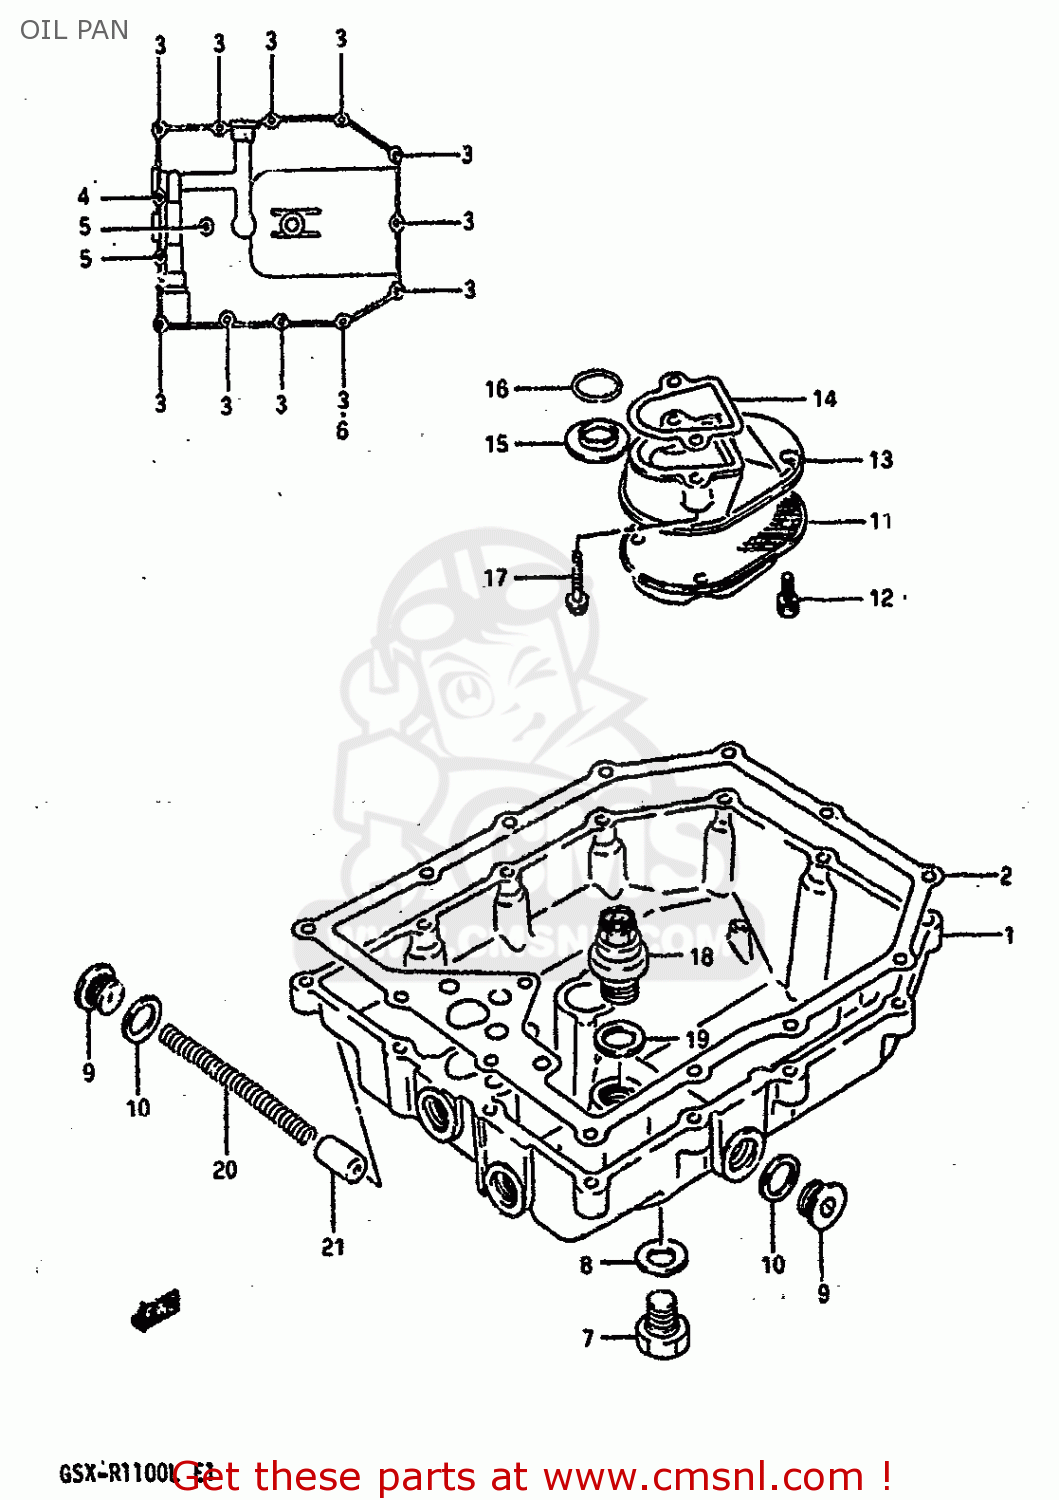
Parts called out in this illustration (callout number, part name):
1	PAN,OIL
2	GASKET,OIL PAN (NA)
3	BOLT
4	BOLT
5	BOLT
6	GASKET(5.8X11X1.2) (NAS)
7	PLUG
8	GASKET(14X19.2X2) (NAS)
9	PLUG
10	GASKET(16X22X2) (NAS)
11	STRAINER,ENGINE OIL
12	BOLT
13	PROTECTOR,OIL STRAINER
14	GASKET,PROTECTOR (NA)
15	GASKET,OIL OUTLET (NAS)
16	O RING(D:3.2,ID:17.8)
17	BOLT
18	VALVE ASSEMBLY,OIL RELIEF
19	GASKET(16X22X2) (NAS)
20	SPRING
21	PLUNGER,OIL CONTROLL
